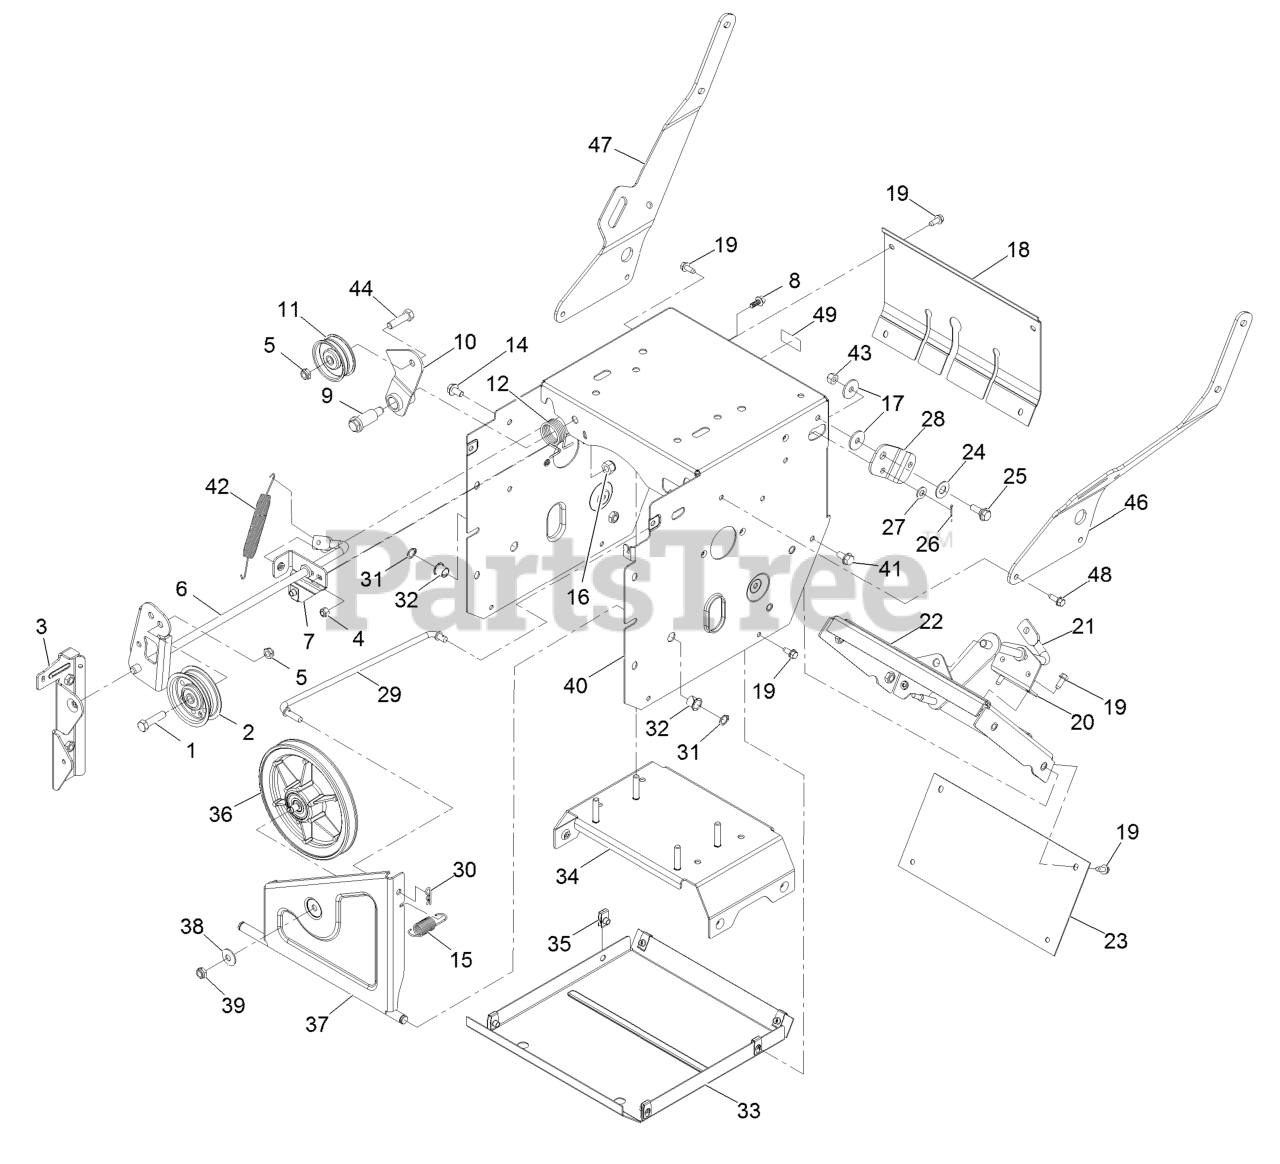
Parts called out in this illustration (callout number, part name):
1	Screw-HH 3/8-16 X 1 1/2
2	Pulley-Idler
3	Bracket-Idler, Impeller
4	Nut-Nyloc 1/4-20
5	Nut-Nyloc 3/8-16 Thin
6	Impeller Clutch ASM
7	Bracket-Clutch, Impeller
8	Screw-HH 1/4-20 X 5/8
9	Bolt-Shoulder
10	Arm-Idler, Traction
11	Pulley-Idler
12	Spring-Torsion
14	Screw-HH Flg 5/16-18 X 5/8
15	Spring-Extension
16	Nut-Lock, NI
17	Washer-Pivot
18	Cover-Upper
19	Screw-HWH 1/4-20 X .62
20	Bracket-Rod, Shift
21	Lever-Control, Traction
22	Shift Plate ASM
23	Cover-Lower
25	Screw-Shoulder 5/16-18 X 1 Sp
26	Pin-Cotter
27	Washer-5/16 Sae
28	Bellcrank-Drive
29	Link-Control, Speed
30	Pin-Cotter
31	Ring-Retaining
32	Bushing-Nyliner
33	Pan-Bottom
34	Brace-Frame
35	Nut-Retainer-Panel 1/4-20
36	Pulley-Traction
37	Bracket-Wheel, Friction
38	Washer-Belleville
39	Nut-Nyloc 3/8-24 Thin
40	Traction Frame ASM
41	Screw-HWHTF
42	Spring-Extension
43	Nut-Nyloc 5/16-18
44	Screw-HH 3/8-16 X 1 3/8
46	Brace-Handle, LH
47	Brace-Handle, RH
48	Screw-HWH, Thread Roll
49	Decal-Patent Ttco.Com
